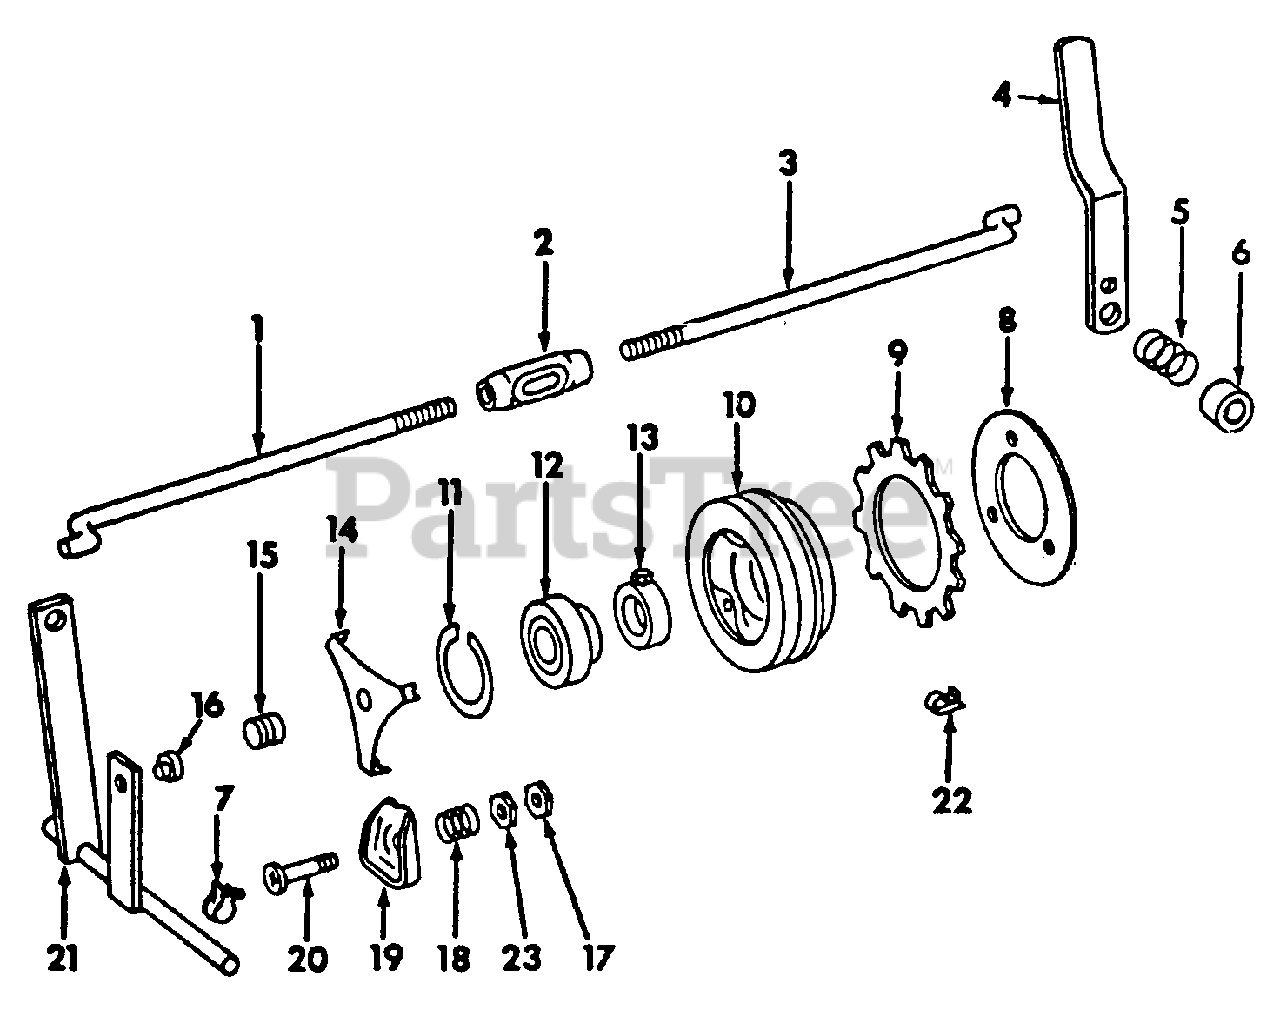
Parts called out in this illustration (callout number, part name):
2	Turnbuckle, Rod
3	Rod, Rear Clutch
4	Lever Assy, Handle
5	Not used in this application
6	Spacer, Handle
7	Clamp, Locating
8	Plate, Pressure
9	Disc, Friction
10	Pulley, Mower Actuating
11	Ring, Snap 2.197 O.D., For Pulley
12	Bearing, Ball
13	Collar w/Set Screw & Lock Nut, Brg
14	Spring, Pressure
15	Button, Thrust
16	Button, Wear
17	Nut, 1/4-28 Hex Jam
18	Spring, Compression
19	Lever, Throw-Out
20	Screw, Special Machine
21	Shaft, Clutch
22	Spring, Friction Disc
23	Nut, 1/4-28 Hex
